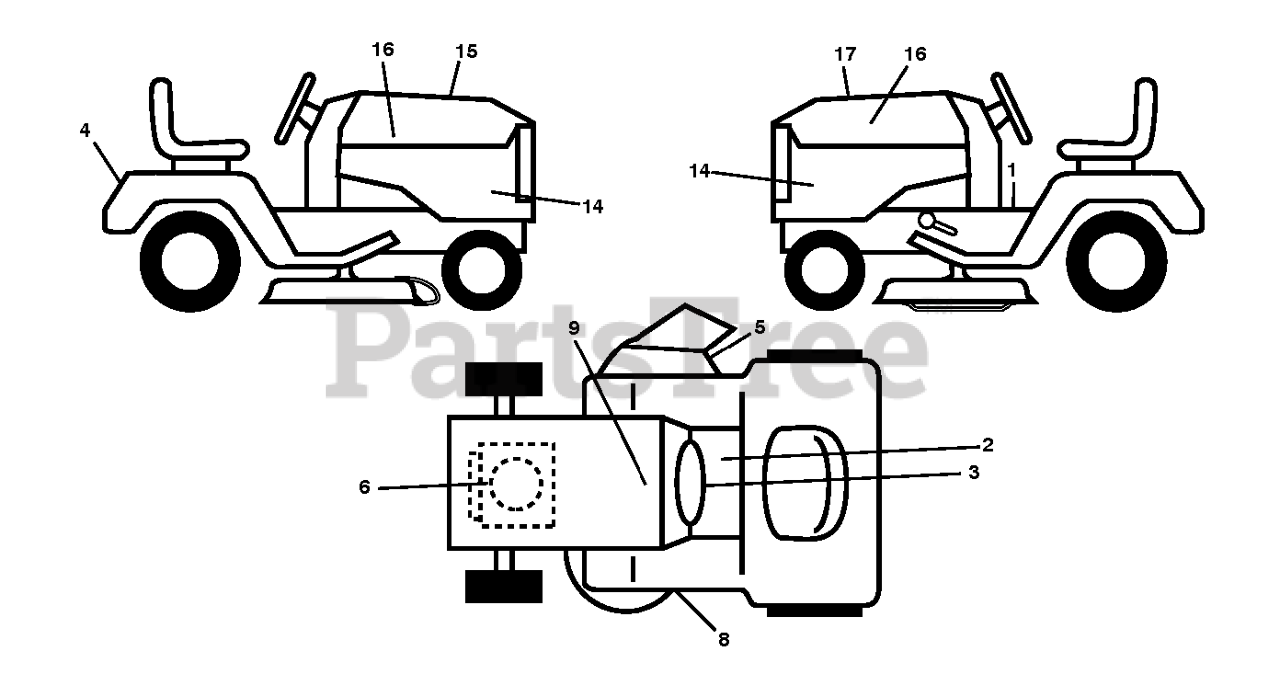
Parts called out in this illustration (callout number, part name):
1	DECAL.WARN.START.INSTRUCTIONS
2	LABEL.EMISS.CA.HUSQ/LOWES.2011
3	DECAL, WARNING SPARK ARRESTOR
4	DECAL.FENDER
5	DECAL.MOWER
6	DECAL.ENG.BS.23HP.XRD.TWIN
8	DECAL.MOWER.SCH.48/54
9	DECAL BTRY SYMBOLS
14	DECAL, PANEL SIDE
15	DECAL.WARNING.CUST.RESP.E85.
16	RP.DECAL.BADGE.170MM.TEXTLOGO
17	DECAL.RPL.BSM44.INK.TLW.48.K4
